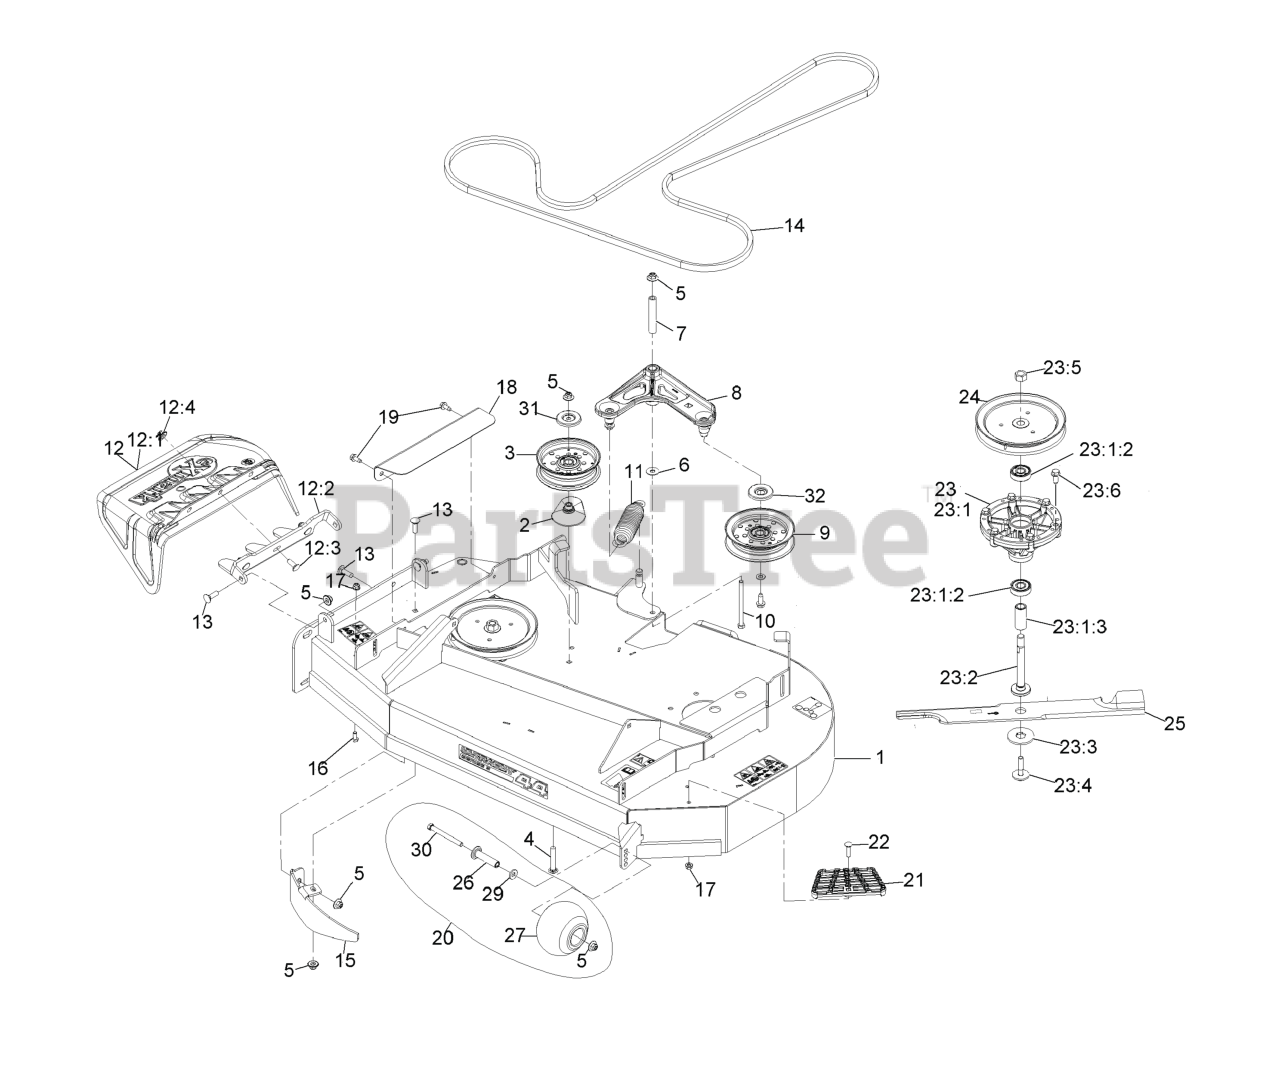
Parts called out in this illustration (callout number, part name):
1	DECK ASM
2	SPACER-PULLEY
3	IDLER-PULLEY, FLAT 5.00X1
4	SCREW-CARR
5	Nut-Nyloc 3/8-16 Flg
7	BUSHING
8	IDLER ARM ASM
9	IDLER-PULLEY, FLAT
10	SCREW-HH
11	SPRING-EXTENSION
12	ASM,DISCHARGE CHUTE
12:1	CHUTE,DISCHARGE
12:2	BRACKET,DISCHARGE CHUTE
12:3	SCREW-CARR
12:4	Nut-Nyloc 3/8-16 Flg
13	BOLT-CARR
14	BELT - V, B
16	SCREW-HH
17	NUT-HF, NI
18	COVER,BELT
19	Screw-HWH 5/16-18 X 3/4 Tf
20	KIT, ANTI-SCALP ROLLER
21	STEP-DECK
22	Bolt-Carriage 5/16-18 X 1 1/4
23	ASM, CUTTER HOUSING COMPLETE
23:1	ASM-CUTTER HOUSING
23:1:2	BEARING
23:1:3	SPACER-BEARING
23:2	SPINDLE-HEX PILOT
23:3	WASHER-HEX BLADE DRIVE
23:4	BOLT-BLADE, SEM
23:5	NUT-HEX
23:6	SCREW-FORMING, THREAD
24	SHEAVE- BLADE DRIVE
25	Blade-Notched, 22.25
25	Blade-Mulch, 22.25
26	AXLE, ROLLER
27	ROLLER-SCALP, ANTI
29	WASHER-BELLEVILLE
30	SCREW-HH 3/8-16 X 3 3/4 GR 8
31	SHIELD-DUST
32	SHIELD-GUARD, DUST
